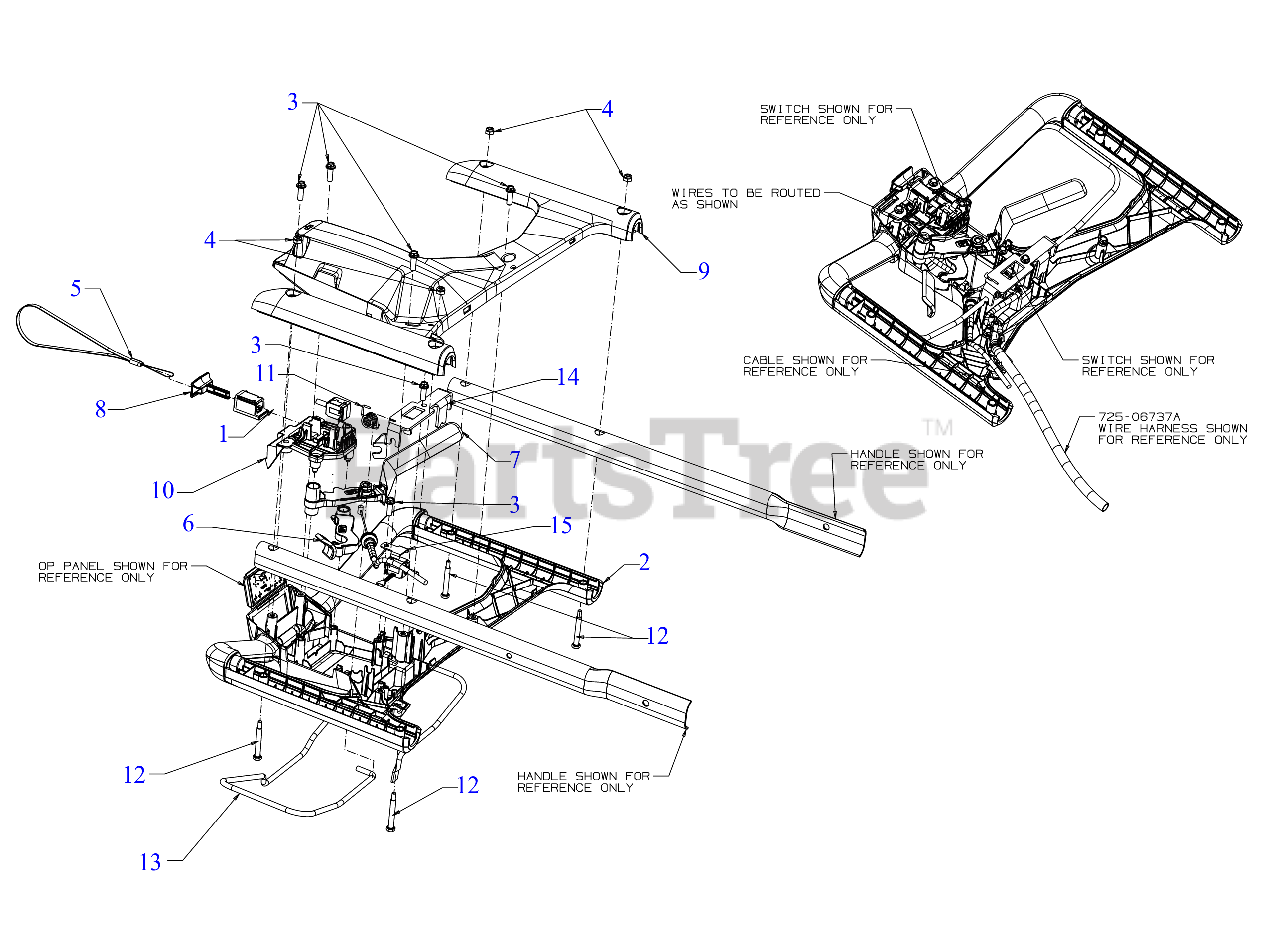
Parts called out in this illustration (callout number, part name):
1	KEY RECEPTICAL ASSEMBLY
2	UPPER HANDLE PANEL ASSEMBLY
3	SCREW 1/4 x .750
5	KEY STRAP CORE
6	CONTROL LEVER (LH)
7	CONTROL LEVER (RH)
9	LOWER HANDLE PANEL
10	KEY RECEPTICLE BRACKET
11	TORSION SPRING
12	SHOULDER SCREW .25:1.63:#10-24:.32
13	CONTROL BAIL
14	BAIL SUPPORT BRACKET (POWDER BLACK)
15	BAIL SWITCH BRACKET
